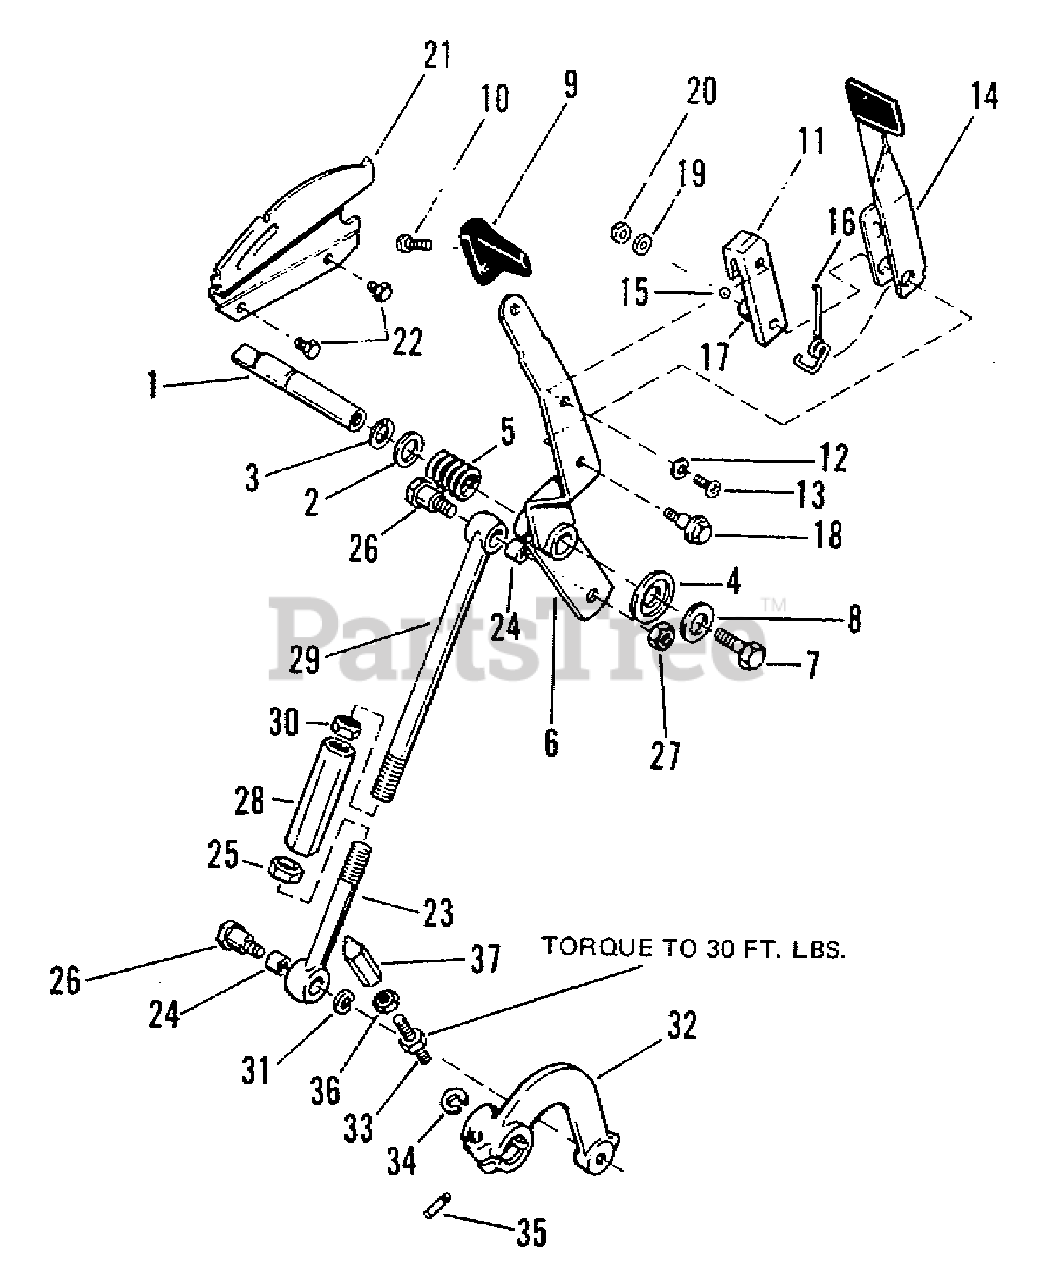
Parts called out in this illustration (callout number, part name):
1	SHAFT, Pivot
3	RING, Retaining
6	LEVER ASSEMBLY
7	CAPSCREW, Hex, 3/8"-16 x 1-1/4" Lg.
10	SCREW, Thread Forming, 1/4-20 x 3/4" Lg.
11	CLAMP, Stop
12	LOCKWASHER, 1/4"
13	SCREW, Phillips, 1/4"-20 x 1/2" Lg.
18	BOLT, Shoulder
19	WASHER, Plain, 1/4"
20	NUT, Hex, Lock, 1/4"-20
22	SCREW, Taptite, 1/4-20 x 3/8
23	BOLT, Eye
25	NUT, Hex, Jam, 1/2"-20
26	BOLT, Shoulder
27	NUT, Hex, Full Lock, 3/8"-16
28	TURNBUCKLE
29	BOLT, Eye
30	NUT, Hex Jam, L.H., 1/2"-20
34	LOCKWASHER, 3/8"
36	NUT, 3/8"-16
